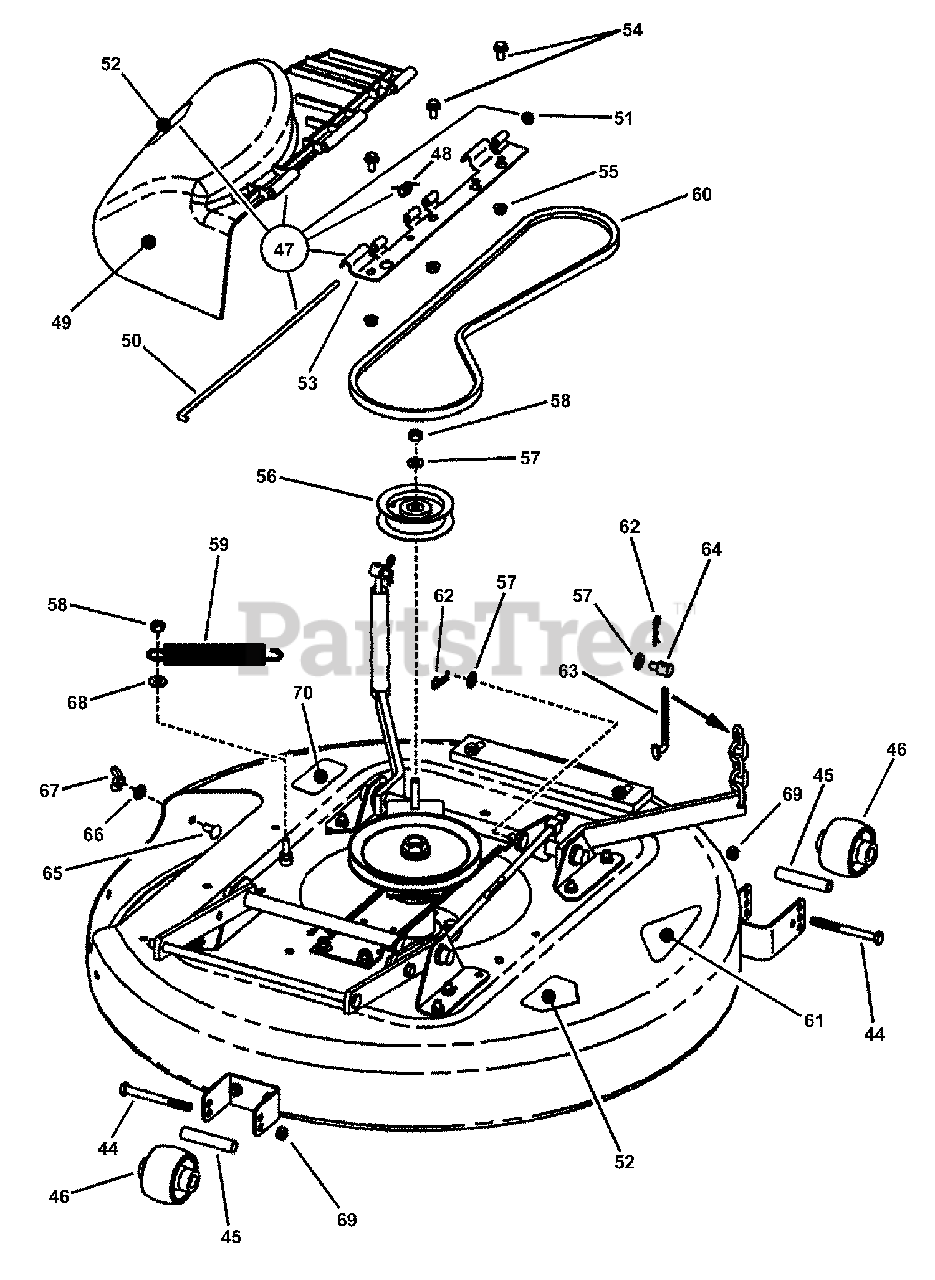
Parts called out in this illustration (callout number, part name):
44	SCREW, 3/8-24 x 3-3/4 Hex Head Cap, GR5
45	SPACER, 3" long
46	WHEEL, Gage
47	ASSEMBLY, Discharge Chute
48	SPRING, Hinge
49	CHUTE, Discharge, 28"/33"
50	ROD, Chute
51	PALNUT WASHER (for .25 dia. rod)
52	DECAL, Danger, Cut Finger (CPSC)
53	HINGE, Plastic Side Chute
54	BOLT, 5/16-18 x 5/8" Hex Flange Lock, GR5
55	NUT, 5/16-18 Hex Flange Lock, GR5
56	IDLER, Flat (4.00 O.D.)
57	WASHER, 3/8" Flat
58	NUT, 3/8-16 Hex Center Lock, GR5 or B
59	SPRING, Extension 1.03 Dia. X 6.8" long
60	BELT, HA Section, 33 DECK (55.2" effective length)
61	DECAL, 33 Hi-Vac
62	HAIR PIN, 3/32 x 1-1/2"
63	ADJUSTER, Chain (5/16-18 thread)
64	SWIVEL, Adjustment
65	BOLT, 5/16-18 x 3/4" Short Neck Carriage, GR5
66	WASHER, 11/32" Flat
67	WING NUT, 5/16-18
68	WASHER, .375 x .875 x .083 Flat
69	NUT, 3/8-24 Hex Center Lock
70	DECAL, Chute/Deflector
